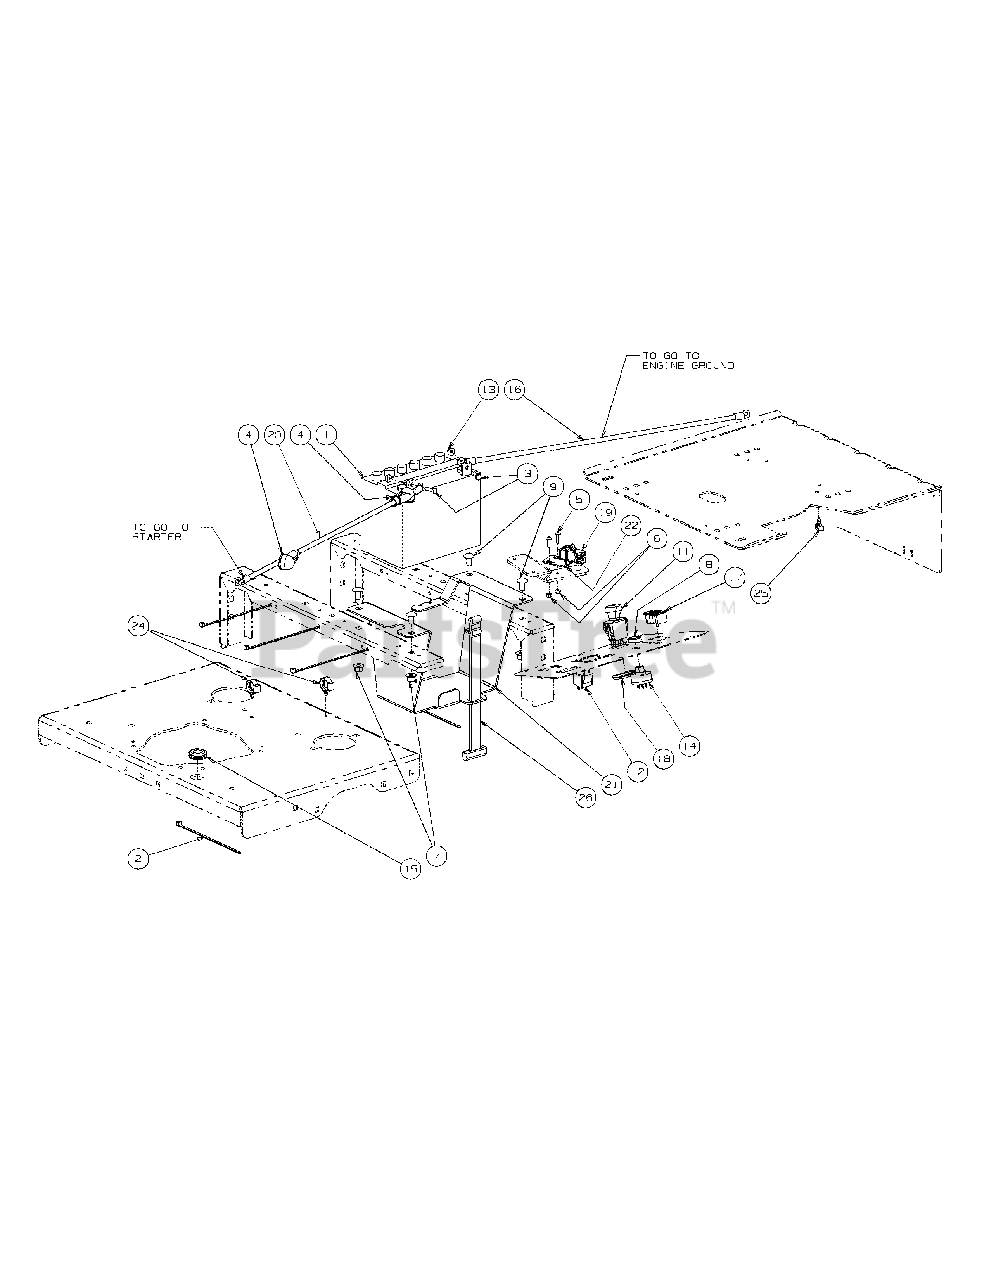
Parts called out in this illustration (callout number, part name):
1	Battery, 12V 225CCA 30 Min
2	Tie, Cable, 3/16 x .05 x 7.4"
3	Screw, Hex, Cap, 1/4-20 x .75
4	Boot, 1" OD Rubber Battery-PST, Red
5	Round Hd. Machine Screw, 10-32 x 3/4
6	Lock Nut, Nylon Insert
7	Flange Lock, Hex Nut, 3/8-16
8	Nut, W/Cap, 5/8-32 Ignition
9	Carriage Bolt, 3/8-16 x .75 Long
11	Switch, Electric, PTO
12	Relay, 12V 40A
13	Lock Nut, 1/4-20
14	Switch, Ignition, 6 Pin includes:
15	Grommet, .75 ID
16	Cable, Battery Red, 28"
17	Meter, Hour includes:
18	Bracket, PTO Switch Retainer
19	Switch, Safety N.O./N.C.
20	Cable, Battery, Red, 42"
21	Battery Bracket
22	Control/Brake Panel Switch
24	Electrical Conduit Clip, 5/8
25	Electrical Conduit Clip, 3/8
26	Strap, Battery
